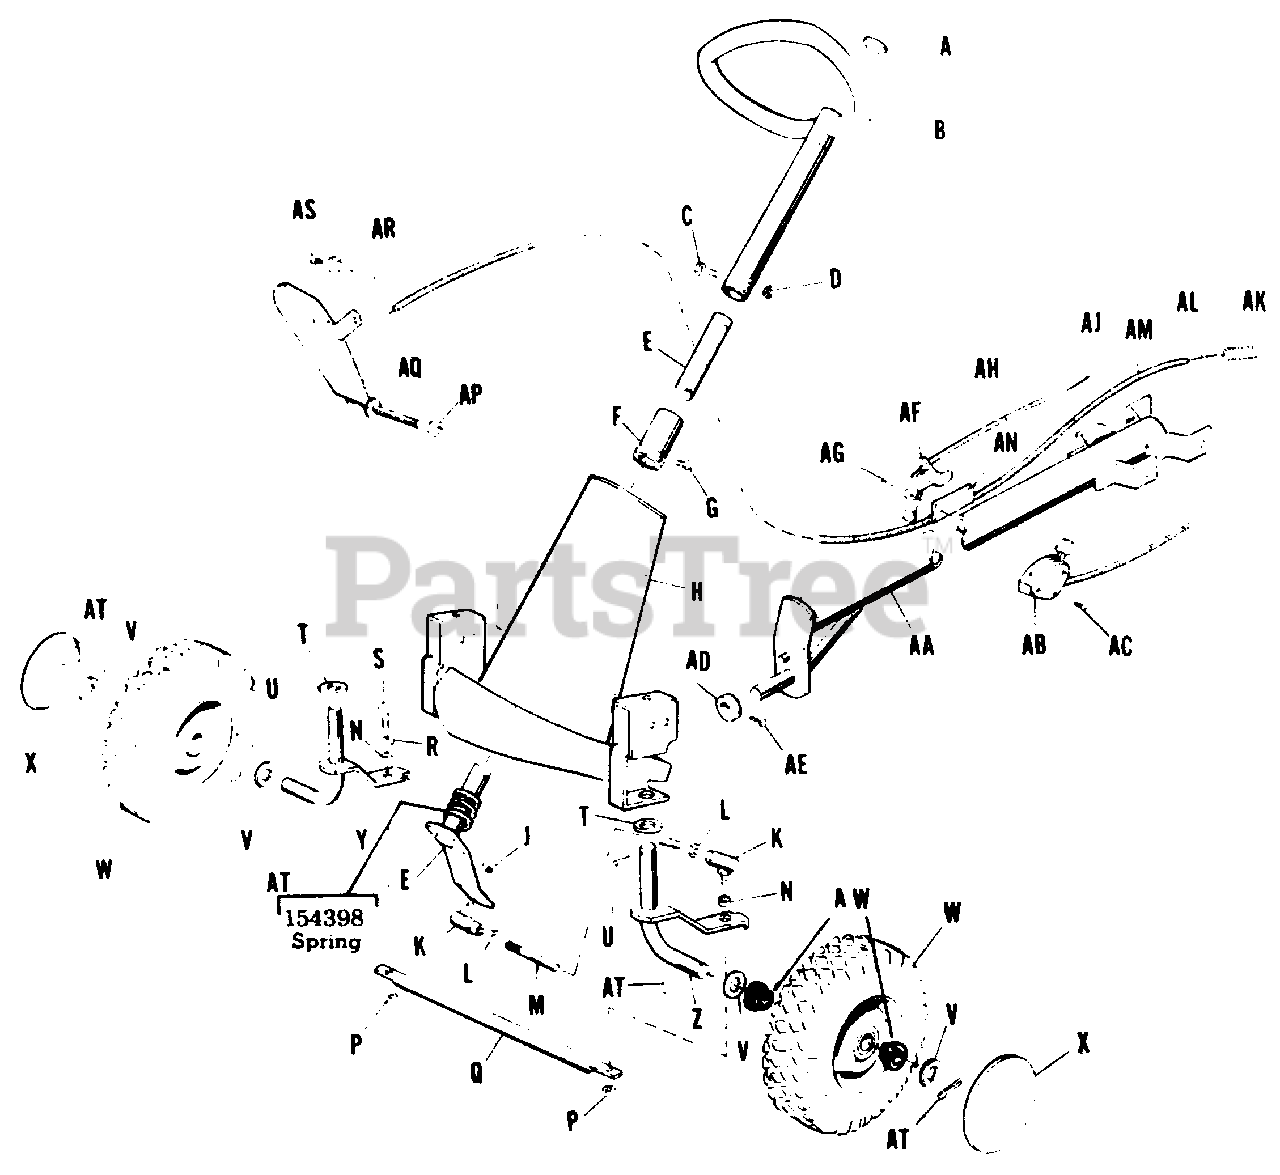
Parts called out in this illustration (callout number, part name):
A	Button, Plug
B	Handle, Steering
C	Capscrew, Hex Hd., 5/16 x 1 1/2
D	Nut, Hex, Full, 5/16-18 NC
E	Arm Assembly, Steering
F	Collar & Tube Assembly
G	Set Screw, S. Hd., Cup Pt. 5/16 x 1/2
H	Support, Steer Rod, Sub Assembly
J	Nut, Lock, Full Hex 3/8-24
K	Ball Joint
L	Nut, Hex Full, 3/8-24
P	Nut, Lock, Full Hex, 3/8-16
Q	Link Drag
R	Washer, Plain, 3/8
S	Capscrew, Hex Hd., 3/8 x 1
U	Cotter Pin
W	Wheel & Tire Assembly
X	Hub Cap, Front
Y	Spindle Assembly, R.H.
Z	Spindle Assembly, L.H.
AA	Frame Assembly, Front
AB	Throttle Control Assembly
AC	Screw, Selt Tapping, 10-24 x 1/2
AD	Collar, Set
AE	Set Screw, Socket Hd., 5/16 x 3/8
AF	Lever Assembly
AG	Screw, Self Tapping, #10-24 x 1/2
AH	Choke Cable
AJ	Choke Wire
AL	Clutch Wire
AM	Clutch Wire Cable
AN	Cable Clamp
AP	Lock Nut, Full Hex, 3/8-16
AQ	Foot Pedal Assembly
AR	Clutch Wire Pivot
AS	Set Screw, Sq. Hd., 1/4-20 x 3/8
AT	Cotter Pin
